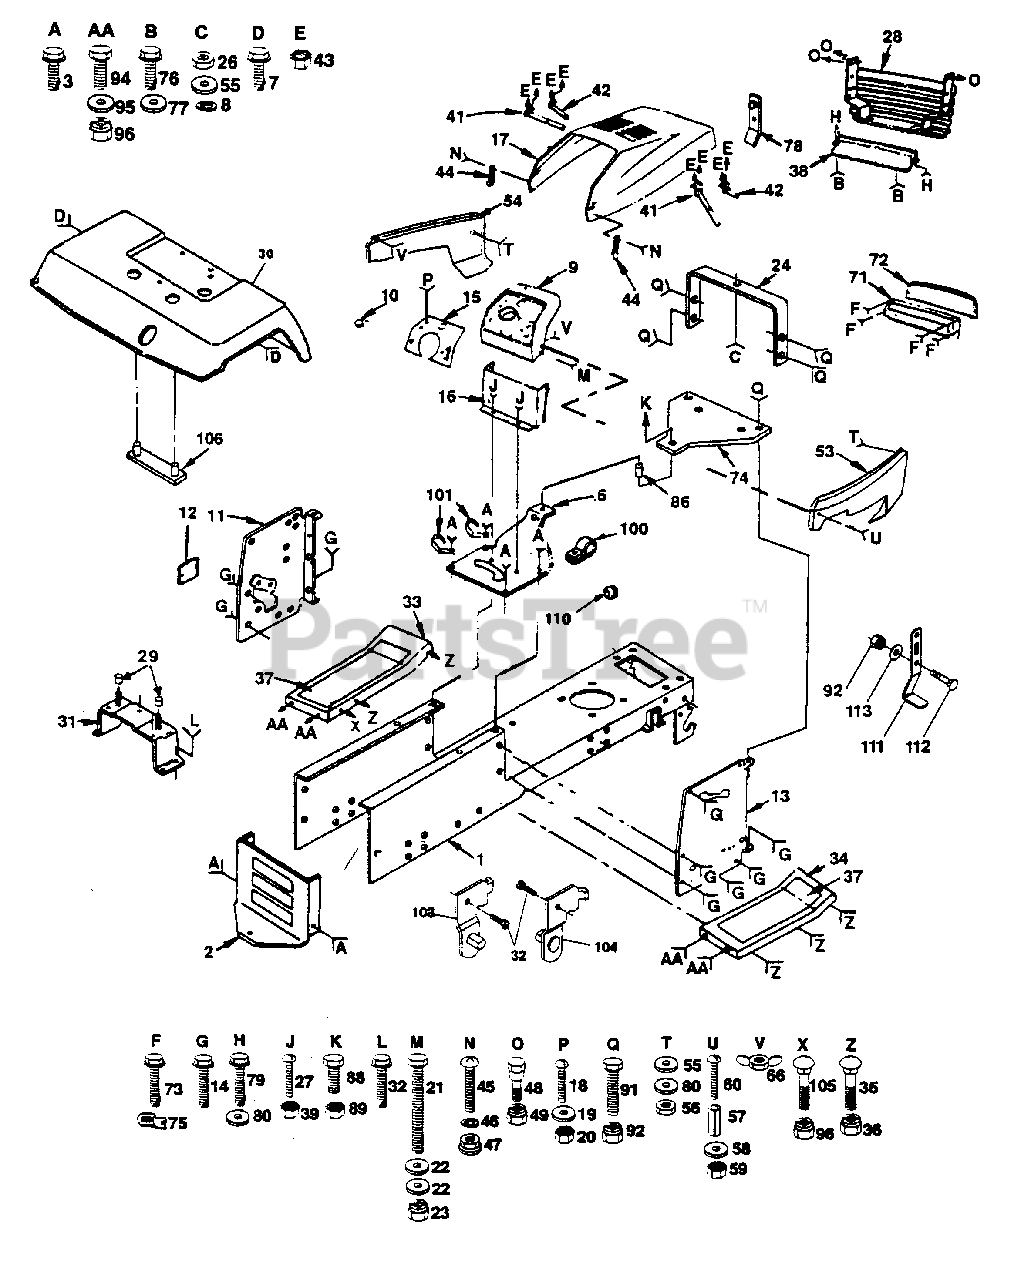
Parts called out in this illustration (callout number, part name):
1	Chassis Weldment 12 ga 38/42 (AYP part number)
2	Drawbar Stretch (AYP part number)
3	Screw Thdrol 3/8 - 16 x 3/4 Ty-TT (AYP part number)
6	Saddle Slkscr (AYP part number)
7	Screw Thdrol 3/8 - 16 x Ty-TT (AYP part number)
8	Washer Lock Hvy. Helical 1/4 (AYP part number)
9	Dash Black Yard Pro (AYP part number)
10	Plug Dash Blk 5009 Dia. E. Lift (AYP part number)
11	Panel Pnt Dash Lh (AYP part number)
12	Cover Access Black Square (AYP part number)
13	Panel Pnt Dash Rh (AYP part number)
14	Screw Thdrol 3/8 - 16 x 3/4 Ty-TT (AYP part number)
15	Plate Silkscreened Dash (AYP part number)
16	Dash Pnt Lower (AYP part number)
17	Hood Pnt (AYP part number)
18	Screw Mach Trhd 5/16 - 18 UNC x 3/4 (AYP part number)
19	Washer 11/32 x 11/16 x 16 Ga (AYP part number)
20	Nut Keps 5/16 - 18 UNC (AYP part number)
21	Bolt Fin Hex 3/8 - 16 UNC x 1-1/4 (AYP part number)
22	Washer 13/32 x 13/16 x 12 Ga (AYP part number)
23	Nut Lock 3/8 - 16 Unc (AYP part number)
24	Support Pnt Dash (AYP part number)
26	Nut Fin Hex 1/4 - 20 Unc (AYP part number)
27	Screw mach Trhd 5/16 - 18 UNC x 3/4 (AYP part number)
28	Grille Asm (AYP part number)
29	Nut Push Nylon (AYP part number)
30	Fender Pnt (AYP part number)
31	Bracket Pnt Fender (AYP part number)
32	Screw Thdol 3/8 - 16 x 3/4 Ty-TT (AYP part number)
33	Footrest Pnt Lh (AYP part number)
34	Footrest Pnt Th (AYP part number)
35	Bolt Rdhd Sht Sqnk 3/8 - 16 x 3/4 (AYP part number)
36	Nut Lock 3/8 - 16 Unc (AYP part number)
37	Pad Footrest (AYP part number)
38	Strap Grille (AYP part number)
39	Nut Keps 5/16 - 18 UNC (AYP part number)
41	Strap Asm Pnt Hinge Rear (blk) (AYP part number)
42	Strap Asm Pnt Hinge Front (AYP part number)
43	Nut Keps Hex 1/4 - 20 UNC (AYP part number)
44	Latch Chute Blk (AYP part number)
45	Screw Mach Cr Pan #10-24 x 1/2 (AYP part number)
46	Washer Lock #10 (AYP part number)
47	Nut Weld .327/.304 #10 - 24 (AYP part number)
48	Bolt, Shoulder 1/4 - 20 UNC (AYP part number)
49	Nut Crownlock 1/4 - 20 UNC (AYP part number)
53	Panel Pnt Rh Side (AYP part number)
54	Panel Pnt Lh Side (AYP part number)
55	Washer 9/32 x 3/4 x 16 Ga (AYP part number)
56	Nut Fin Hex 1/4 - 20 Unc (AYP part number)
57	Spacer Split #10 x 3/4 Cad/Zin (AYP part number)
58	Washer 7/32 x 1/2 x 18 Ga (AYP part number)
59	Nut Keps #10 - 24 Unc (AYP part number)
60	Screw Mach Cr Pan #10 - 24 x 1-1/4 (AYP part number)
66	Nut Plastic Locking Wng 1/4 - 20 (AYP part number)
71	Bezel Asm. Pnt
72	Lens Headlight Bar Clear (AYP part number)
73	Screw Hex Whd Tap #10-16 x 5/8 (AYP part number)
74	Plate Pnt Sprt Battery (blk) (AYP part number)
75	Fastener "J" (AYP part number)
76	Screw Thdrol. 5/16-18 x 3/4
77	Washer 13/32 x 3/4 x 10 Ga. (AYP part number)
78	Bracket Grille Galv
79	Screw Hex Wsh 1/4-20 Unc x 3/4 (AYP part number)
80	Washer 9/32 x 5/8 x 16 Ga. (AYP part number)
86	Spacer Split 59/ x 1.25 Blk/zin (AYP part number)
88	Bolt Fin Hex 5/16 - 18 x 2 (AYP part number)
89	Nut Lock Hx w/Ins. 5/16 - 18 (AYP part number)
91	Bolt Hex 3/8 - 16 x 3/4 (AYP part number)
92	Nut Lock 3/8 (AYP part number)
94	Bolt Fin Hex 3/8 - 16 Unc x 1 (AYP part number)
95	Washer 13/32 x 13/16 x 12 Ga (AYP part number)
96	Nut Lock 3/8 - 16 Unc (AYP part number)
100	Clip Line Fuel 13/32 Mtg Hole (AYP part number)
101	Clip Insulator (AYP part number)
103	Bracket Asm Pivot Lh (AYP part number)
104	Bracket Asm Pivot Rh (AYP part number)
105	Bolt Carriage (AYP part number)
106	Strap Asm. Fender (AYP part number)
110	Bushing Snap Split (AYP part number)
111	Stop Over Center (AYP part number)
112	Bolt Carriage 3/8-16 x 1 (AYP part number)
113	Washer 13/32 x 1 x 12 Ga. (AYP part number)
